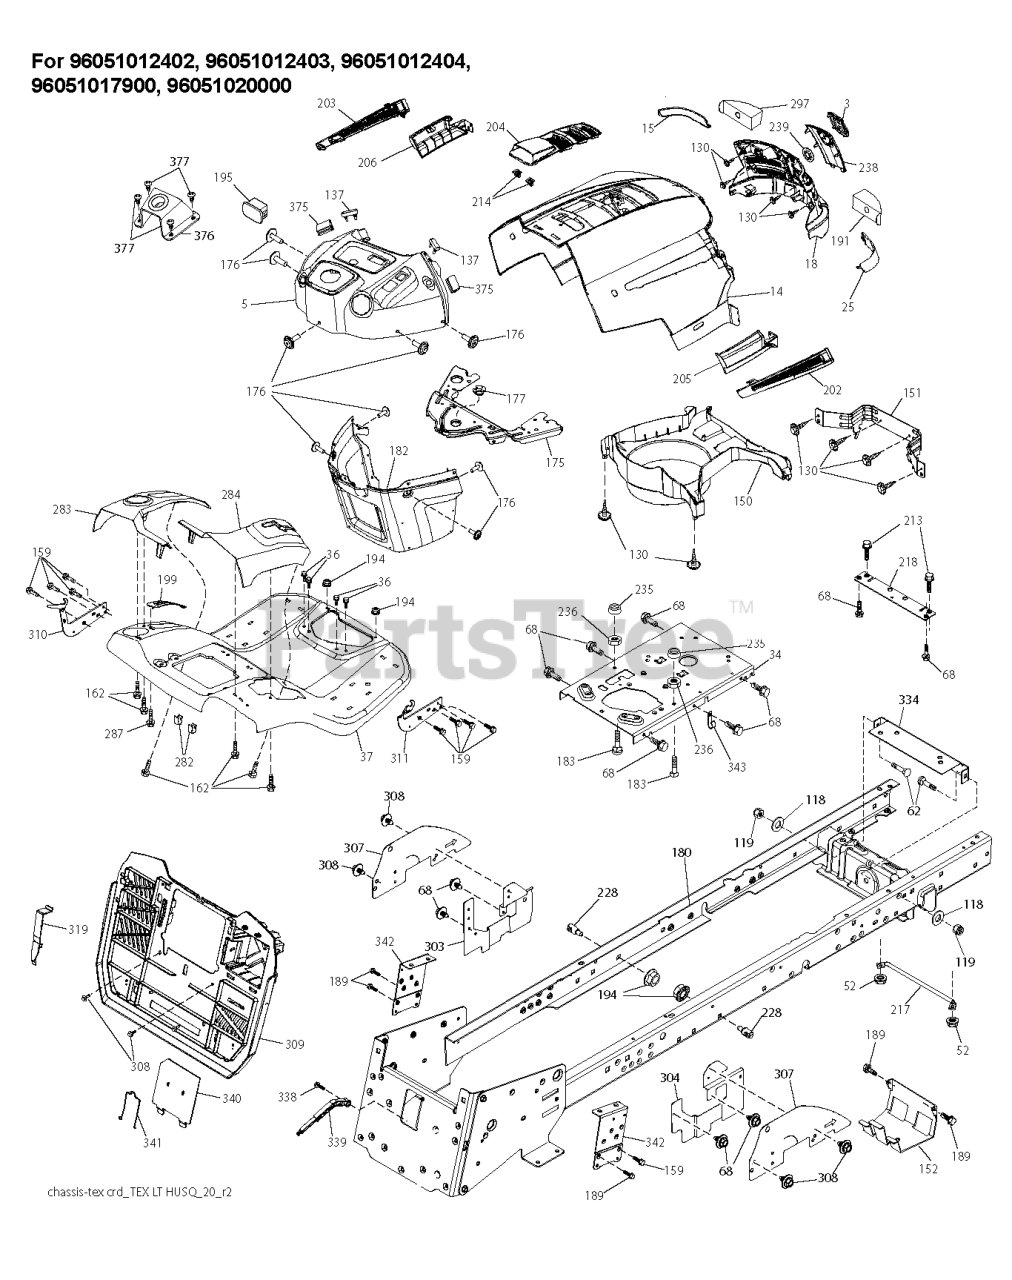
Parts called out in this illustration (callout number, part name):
3	LOGO.HUSQ.GT.LT.CROWN.H
5	DASH.UPPER.HUS.LT.CABLE.CLUTCH
5	DASH.UP.HU.LT.CBL.CLTCH.CHG.PT
5	SUBASM.DASH.UPPER.W/BUMPER
14	HOOD.HUSQVARNA.LT.ORANGE
15	LENS.HUSQVARNA LT.RH
18	GRILLE.SVC.HUSQVARNA.GREY
18	ASM.GRILLE HUSQVARNA.LT.498
25	LENS.HUSQVARNA LT.RH
36	SCREW 5/16"
37	FENDER.TEX.SRD.CRD.BASE
68	Screws
68	BOLT.5/16-18UNCX3/4 W/SEMS.BLK
118	WASHER PLAIN WASHER 3/8 X 0.08
118	WASHER
119	Nuts
119	LOCKNUT
137	BUMPER DASH
151	BRACKET PIVOT
152	SHIELD.BROWNING.W/TEX
159	SCREW, 3/8-16X3/4
159	BOLT
175	CROSSMEMBER
176	SCREW.#10-24X5/8.RN.QU
177	BUSHING STEERING
180	CHASSIS WLDT TEX CRD
182	DASH.LOWER.PREDATOR LT
189	SCREW
191	INSERT.REFLECTIVE.RH.
194	NUT LOCK HEX FLANGE 5/16-18
194	GSPW Nuts
195	PLUG.TEX.DASH.SVC.MINDER.GREY
199	PLATE DECK LIFT
202	VENT.SIDE.HUSQVARNA.LT.RT
203	VENT.SIDE.HUSQVARNA.LT.LFT
204	SUBASM.TOP.VENT.HUSQ.LT
205	SKIRT.SIDE.HUSQVARNA.LT.RT
206	SKIRT.SIDE.HUSQVARNA.LT.LEFT
213	SCREW HEXAGON HEAD SCREW 5/16-
214	CLIP.RETAINER.TINNER.
217	ROD.PIVOT.HOOD
218	X-PIECE.HOOD.STOP.NON/
228	STUD.W/"D"ANTI-ROTATION
236	NUT.CENTERLOCK.5/16-
238	TRIM.HUSQ LT.668
282	CLIP.RETAINER.CONSOLE.LT.HUSQ
283	CONSL.DECKLIFT.LH.SRD.TEX.CRD
284	CONSL.SHFT.PEDAL.RH.SRD.TEXCRD
287	SCREW 1/4X20
297	INSERT REFLECTIVE
303	SHIELD.LWR.LH.30DECK/CRD1&2
303	SHIELD.LWR.LH.LT.30DECK.CRDSRD
304	SHIELD.LOWER.RH.CRD.GEN.PNT
304	SHIELD ISO RH LOWER CRD GEN 1
307	SHIELD.UPPER.CRD.SRD.ISO
308	BOLT.5/16-18UNCX3/4 W/SEMS.BLK
309	BACKPLATE.TEX.CRD.GEN.1
309	BACKPLATE.TEX.CRD
310	LH.ADJUST.HANGER.BRACKET.ASM
311	RH.ADJUST.HANGER.BRACKET.ASM
319	BRACKET.ACTUATOR.BAGGER.SRD
334	BRACKET.ENGINE
338	BOLT BOLT SHOULDER
338	Bolts
339	LEVER LEVER BAGGER
340	DOOR.PNT.BATTERY.TRY.TEX.CRD.
341	LATCH.BATTERY.DOOR.TCRD
342	SUPPORT.PNT.FENDER.CRD.TEX
343	CLIP CLIP
375	BUMPER CLIP-ON. DASH 1"
376	MOUNT.ASM.HUSLT.UPPER.STRNG
377	SCREW 10 X 1/2 ZN PL PHIL PAN
